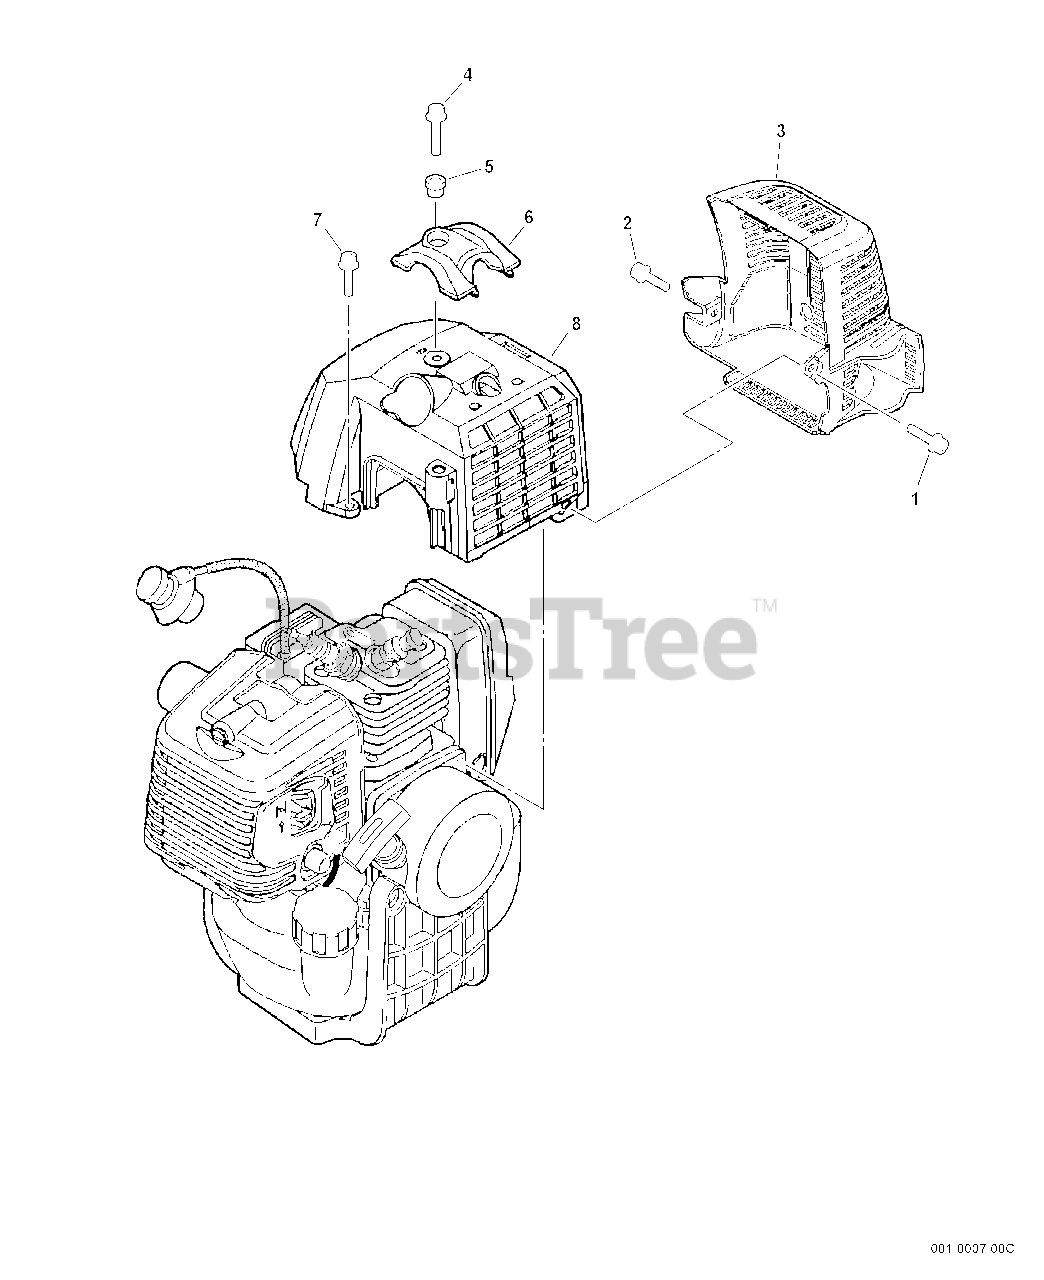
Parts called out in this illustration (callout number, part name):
1	SCREW - 5X20
2	SCREW - 5X12
3	COVER, EXHAUST
4	SCREW - 5X20
5	COLLAR - 5
6	GUARD - TOP
7	SCREW - 5X12
8	COVER, ENGINE - ORANGE
